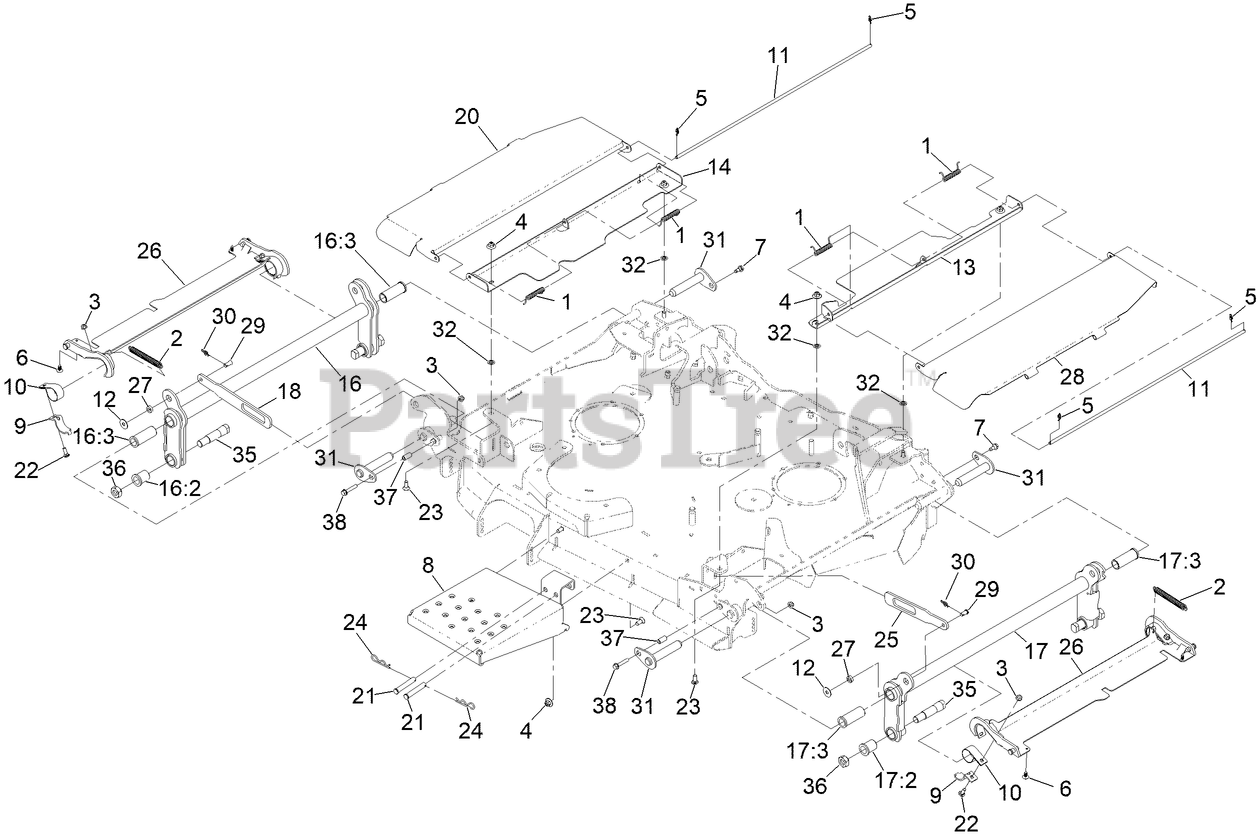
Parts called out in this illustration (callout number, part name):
1	SPRING-TORSION
2	SPRING
3	NUT-HF, NI
4	NUT-FLANGE, NI
5	PIN-COTTER, LOCKING
6	PLUG-PLASTIC
7	SCREW-SHOULDER
8	PLATE-DECK STEP
9	PLATE-RETAINER, BEARING
10	BEARING-STRAP, NYLON
11	COVER-ROD, PIVOT
12	WASHER
13	SHIELD-CENTER, LH
14	SHIELD-CENTER, RH
16	ASM-RH FOLD ARM
16:2	BUSHING-FLANGED
16:3	BUSHING-FLANGE
17	ASM-LH FOLD ARM
17:2	BUSHING-FLANGED
17:3	BUSHING-FLANGE
18	STRAP-RH FLAG
20	PANEL-SHIELD HINGE, RH
21	PIN-CLEVIS
22	SCREW-CARR
23	BOLT-CARR
24	PIN-HAIR
25	STRAP-LH FLAG
26	ASM-WING COVER, [RED]
27	BUSHING
28	PANEL-SHIELD HINGE, LH
29	PIN-CLEVIS
30	PIN-COTTER, LOCKING
31	ASM-DECK PIN
32	NUT-PUSH
35	BOLT-PIVOT PIN
36	NUT-LUG
37	TUBE-STANDOFF
38	SCREW-HWH
